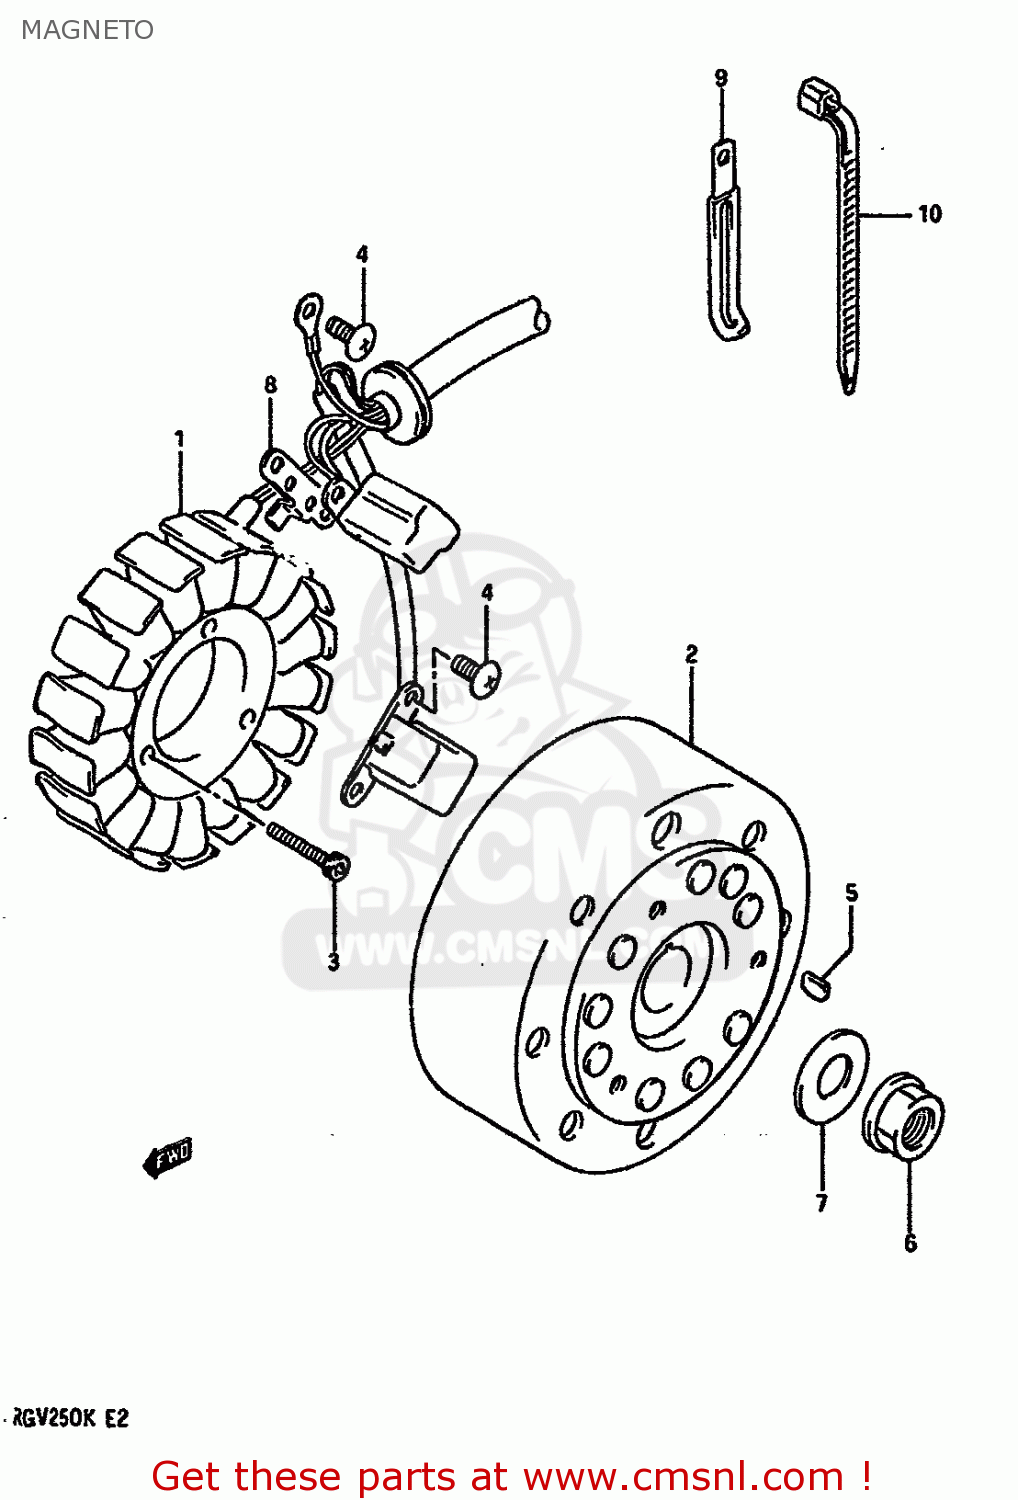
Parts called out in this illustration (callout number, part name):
1	STATOR ASSY
2	ROTOR
3	BOLT,MAGNETO STATOR
4	SCREW
5	KEY
6	NUT
7	WASHER(12X27X2)
8	CLAMP,GENERATOR LEAD WIRE
9	CLAMP
10	CLAMP(L:165)
